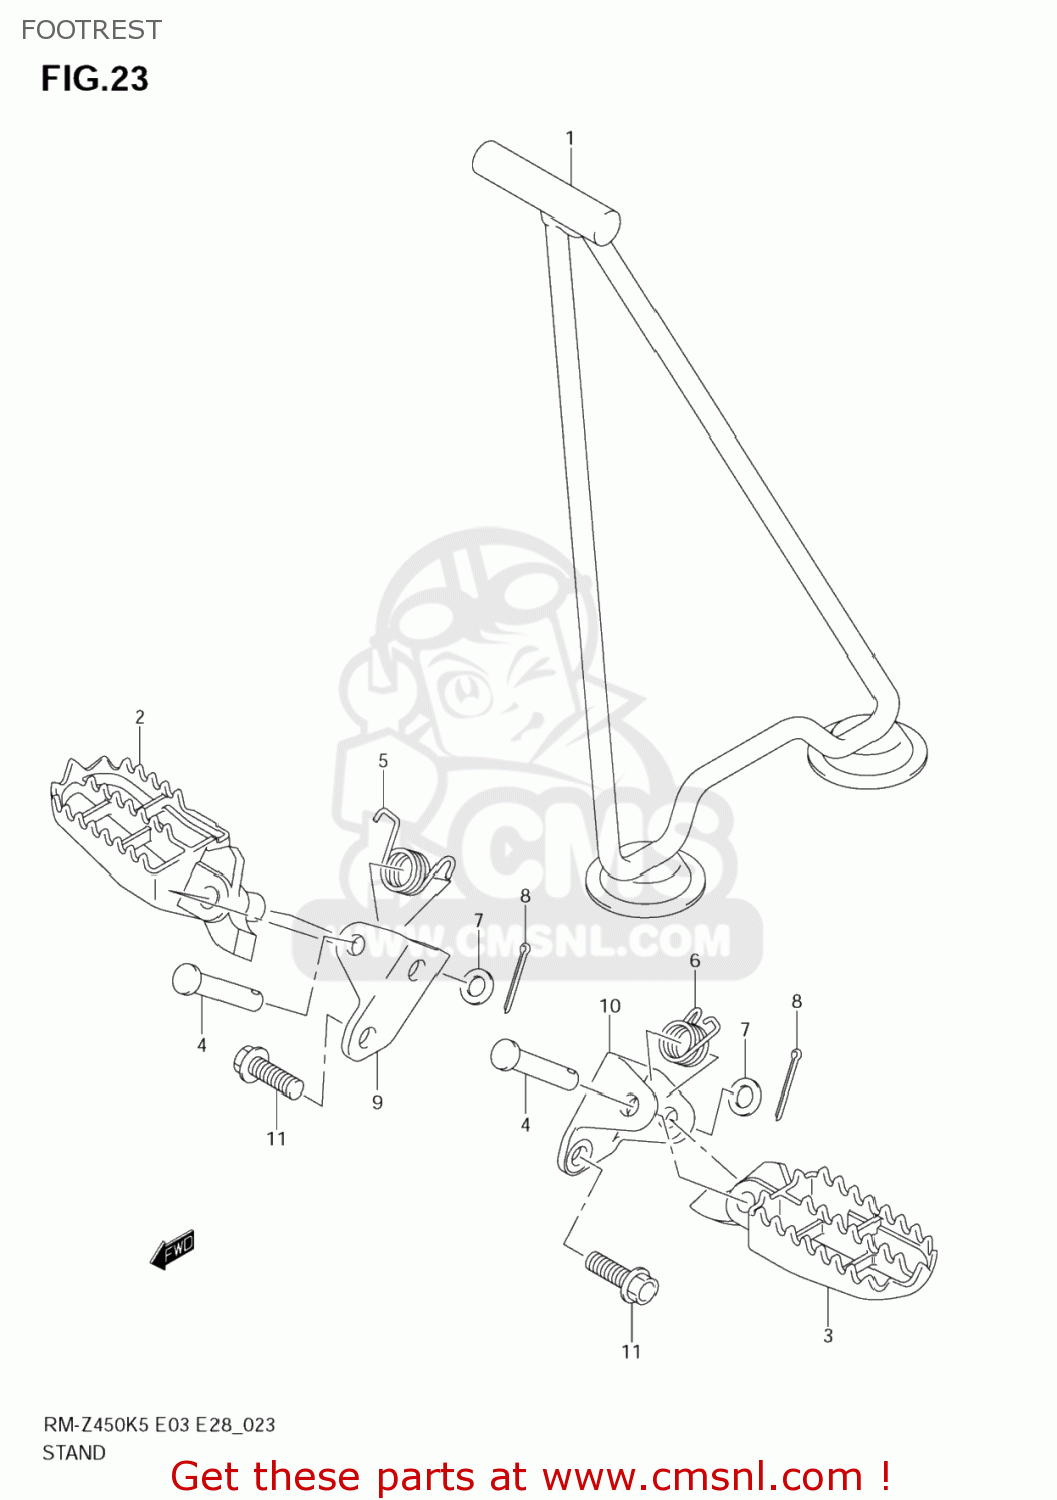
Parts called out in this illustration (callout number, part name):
1	STAND
2	FOOTREST,R
3	FOOTREST,L
4	PIN
5	SPRING
6	SPRING
7	WASHER
8	PIN
9	BRACKET,FOOTREST,R
10	BRACKET,FOOTREST,L
11	BOLT(10X30)
